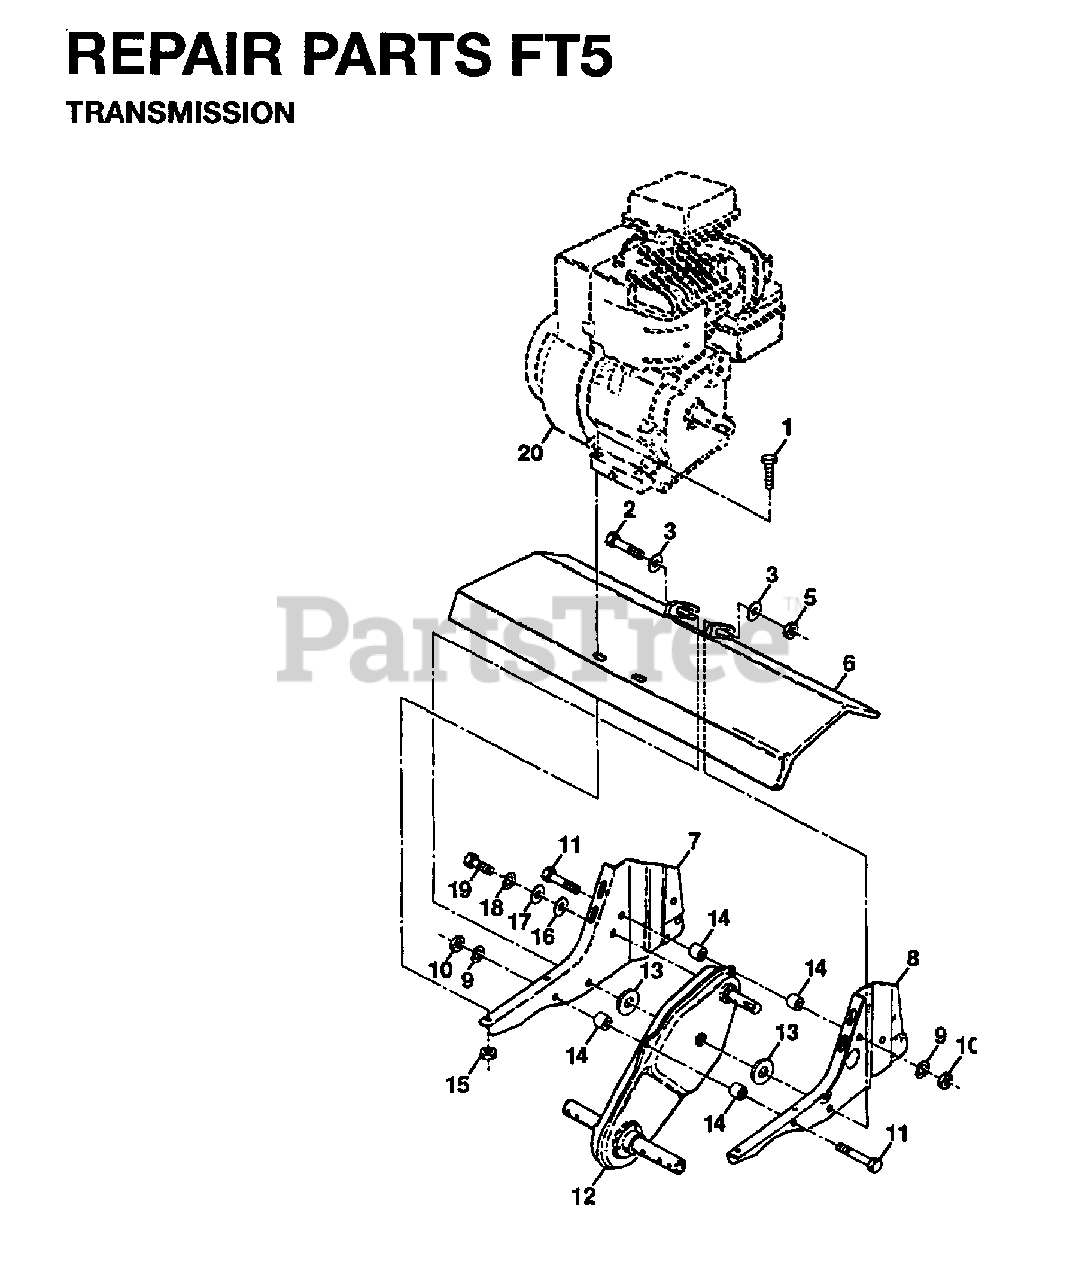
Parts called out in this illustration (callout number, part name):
1	HEX BOLT
3	WASHER
5	LOCKNUT
9	LOCKWASHER
11	BOLT HEX**
12	TRANSMISSION
13	WASHER - M12
15	LOCKNUT
18	LOCKWASHER
